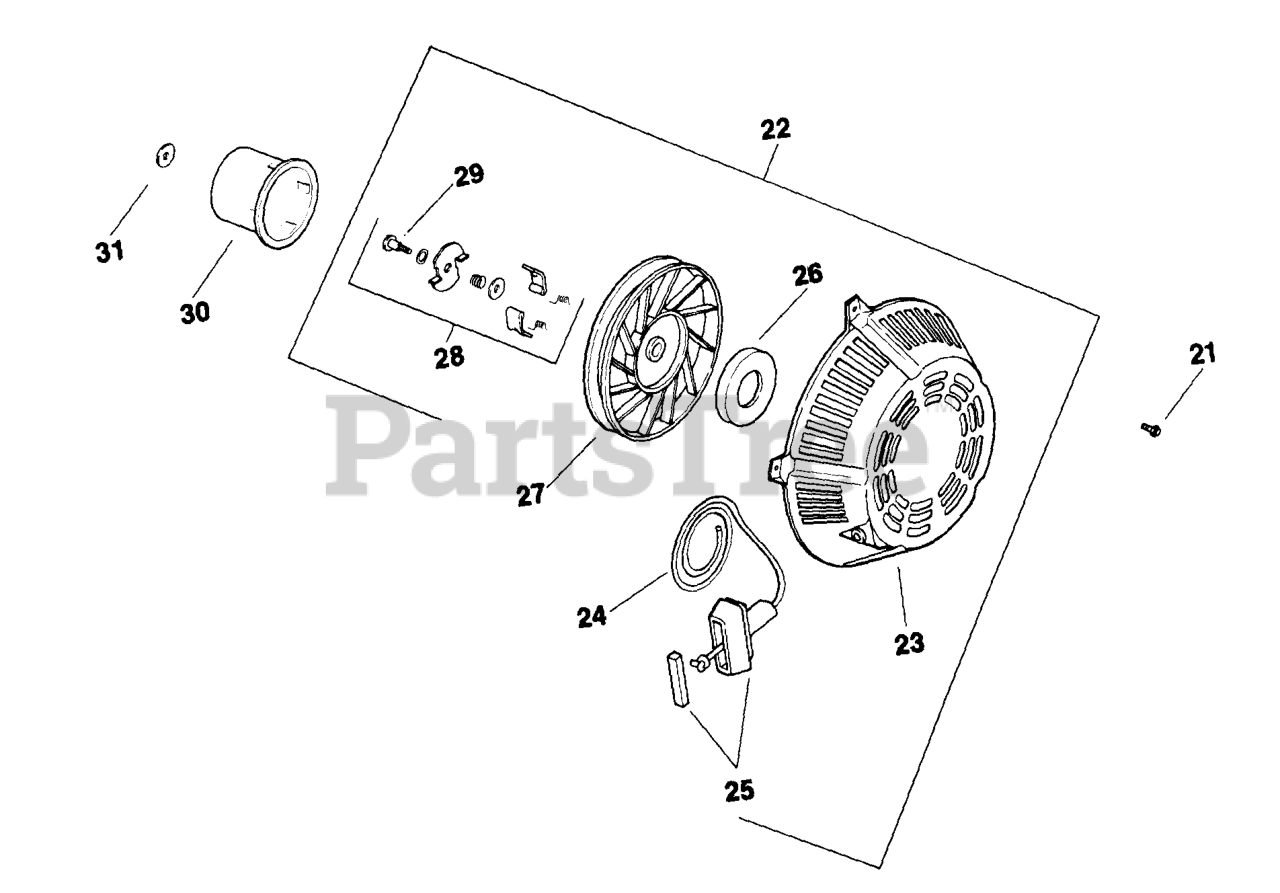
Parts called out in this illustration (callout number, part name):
21	SCREW, FLG HD 10-24X1/4"
22	STARTER ASSY,RETRACTABLE-USE 12 165 03-S
23	HOUSING - DISCONTINUED
24	ROPE - DISCONTINUED
25	HANDLE - USE 25 166 01
26	SPRING & KEEPER - (#DSC)
27	PULLEY - (#DSC)
28	KIT, DOG REPAIR - (#DSC)
29	SCREW - DISCONTINUED
30	CUP
31	WASHER, FLAT 13/32" - DISCONTINUED
